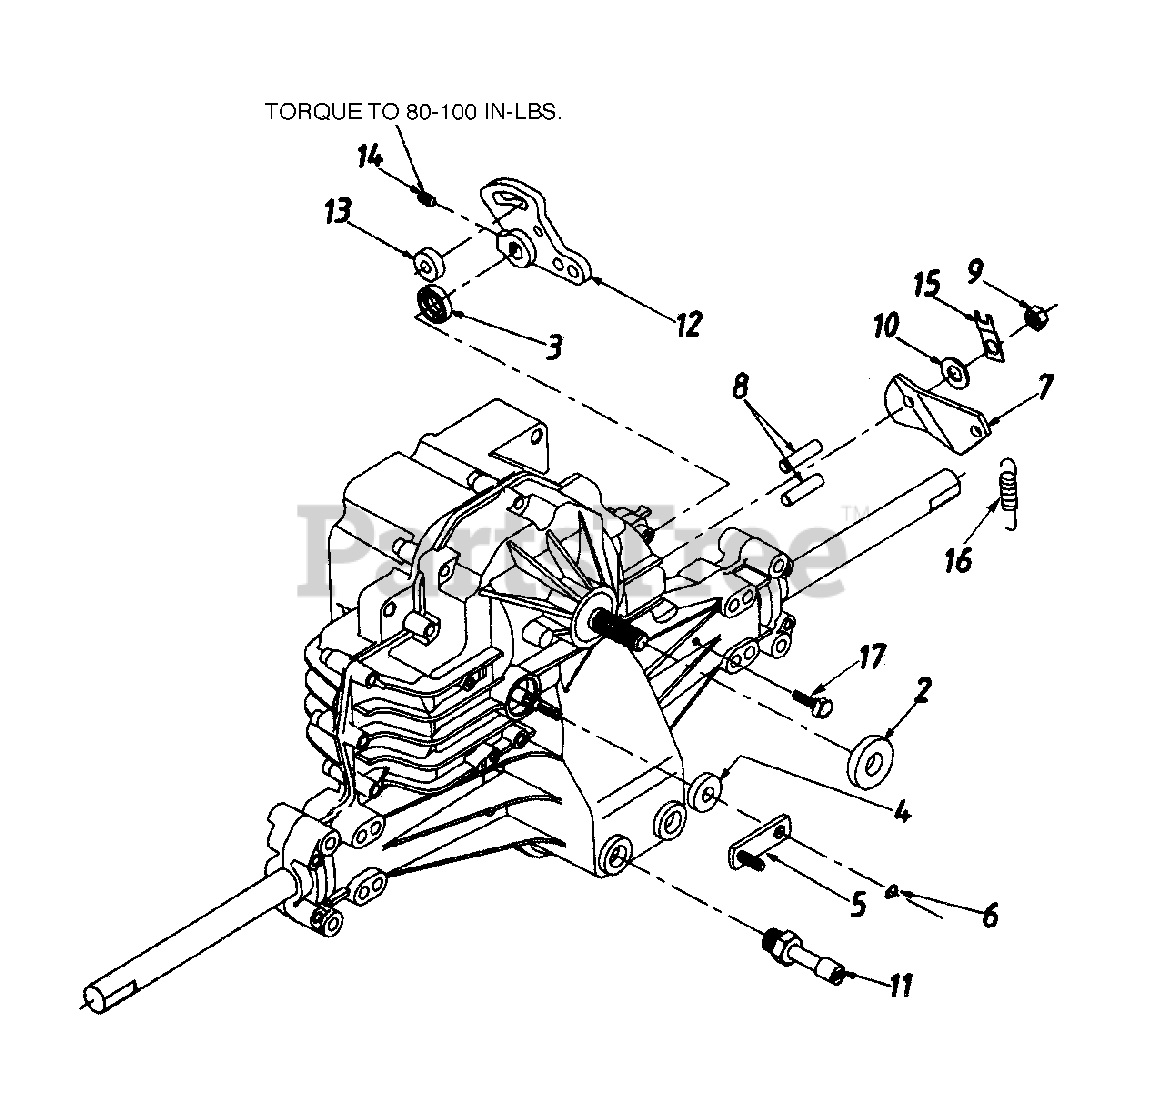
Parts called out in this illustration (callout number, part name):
4	Seal- Lip 10X25X7
5	Bypass Arm
6	Retaining Ring
7	Actuating Arm
8	Actuating Pin
9	Nut-Hex Lock 5/16-24
10	Washer 7/16" x 7/8" x .06"
11	Breather Assembly
12	Arm-Control
13	Puck-Dampener
14	Set Screw
16	Extension Spring
17	Self Tapping Scr. #10-32
